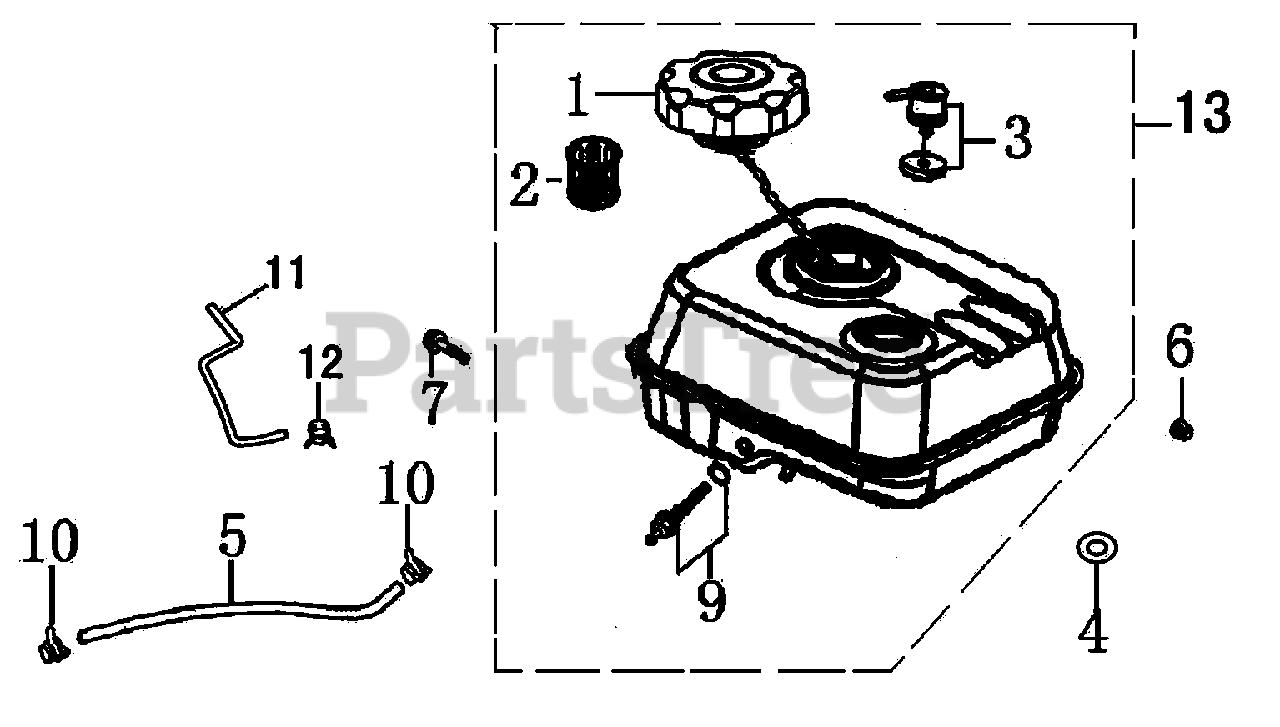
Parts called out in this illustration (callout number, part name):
1	CAP FUEL FILLER
2	FILTER, FUEL
3	ROLL OVER VALVE
4	WASHER, RUBBER
5	HOSE, FUEL
6	NUT, FLANGE
7	BOLT, FLANGE 6X25
9	JOINT ASSY. , FUEL TANK
11	HOSE, FORMED
12	CLAMP/COLLAR
13	TANK ASSY., FUEL W/ROV
